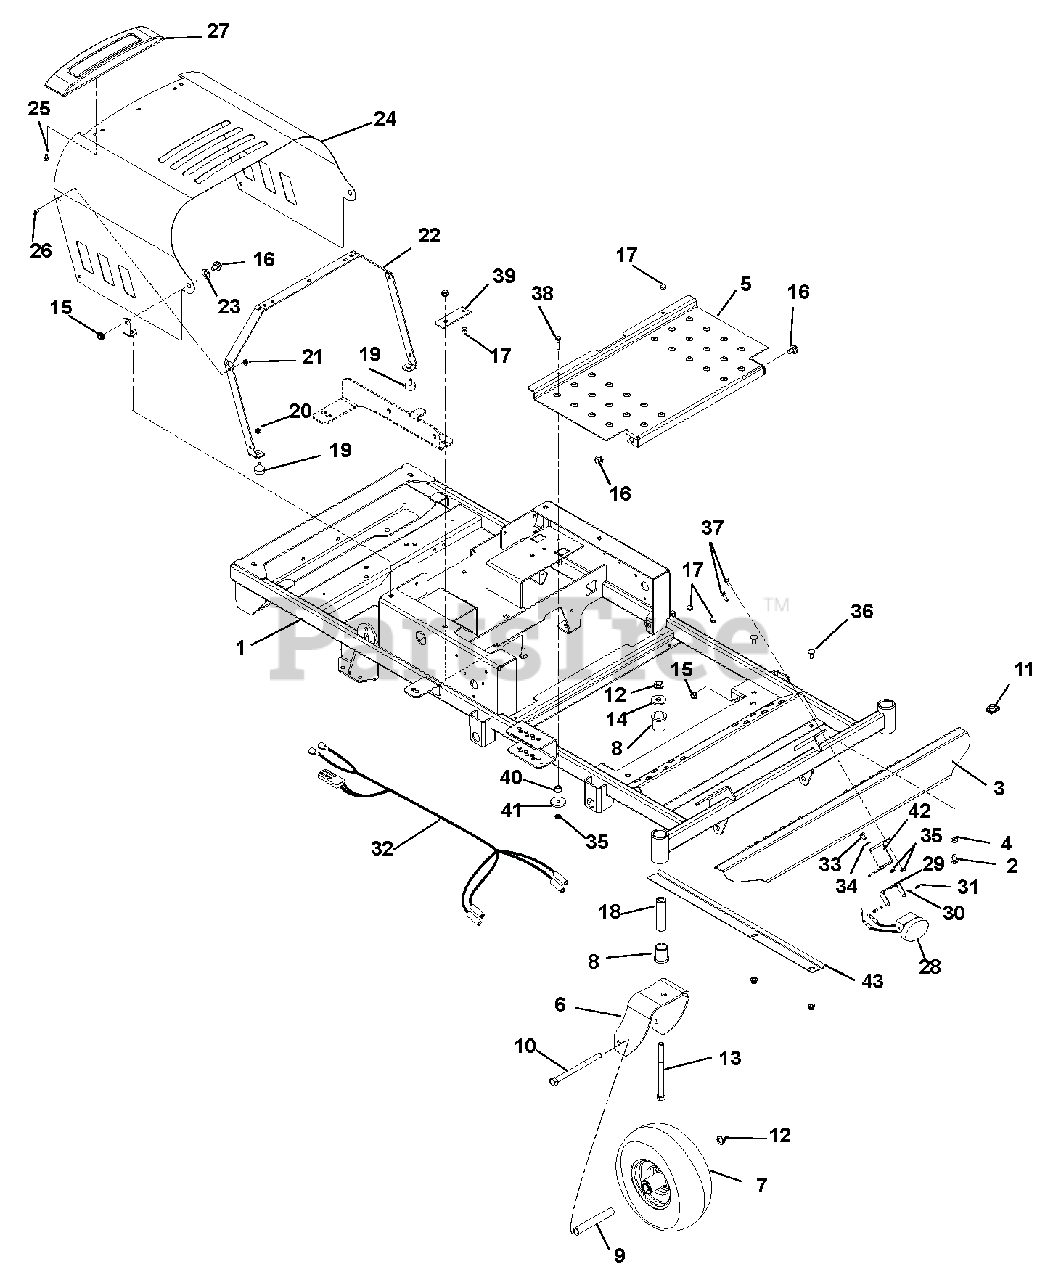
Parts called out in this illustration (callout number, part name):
1	WMT, FRAME XL
2	@BLT-HEX .38-16X1.00 GR5 YWZC
3	WMT, FOOTREST
4	@WSHR-LK .38X.094 REG YWZC
5	DECK ACCESS PANEL
6	CASTER FORK WELDMENT
7	TIRE/WHEEL ASSY, 11X4-5
8	BSHG-FLG 1.00X1.25X1.50X1.50EP
9	SPACER, ROLLED WHEEL
10	@BLT-HEX .50-13X6.50 GR5 YWZC
11	NUT-RTNR .375-16X.37
12	@NUT-LK-TOP-FLG .50-13 YWZC
13	@BLT-HEX .50-13X5.00 GR5 YWZC
14	WSHR-FL-STL.511X1.441X.125 YWZ
15	@NUT-LK-TOP-FLG .38-16 YWZC
16	BOLT-SHLDR .375-16X.150
17	BUMPER GROMMET
18	SPACER, CASTER .50X1.00X1.84
19	BUMPER, RUBBER
20	@NUT-LK-TOP-FLG .31-18 YWZC
21	@NUT-LK-TOP-FLG .25-20 YWZC
22	HOOD STRAP
23	WSHR-FL-NYL .518X1.000X.080
24	HOOD-ZTXL
25	SCR-.25X.62 PN HD BOSSSCREW YZ
26	@BLT-RDHDSQNK .25-20X.50 G5YZ
27	TRIM-ZOOM XL HOOD ARIENS
28	KIT, ZOOM/ZT XL LIGHT
29	WMT, LIGHT BRACKET
30	WSHR-LK 4MMX1MM REG CL ZINC
31	SCREW-M4X.07X8 SHCS CLZNC
32	HARNESS,MINI-Z HEADLIGHT
33	SCR-CAP BTHD.31-18X.50 GR5 YZ
34	@WSHR-LK .31X.078 REG YWZC
35	@NUT-LK-NYL-FLG .25-20 YWZC
36	@BLT-RDHDSQNK .31-18X.75 G5YZ
37	@BLT-HEX .25-20X.75 GR5 YWZC
38	@BLT-HEX .25-20X1.25 GR5 YWZC
39	STRAP, SEAT HOLD DOWN (CE)
40	SPACER .325 X.625 X.455
41	WSHR-FL-STL .281X1.50X.187
42	BRACKET, LIGHT MOUNT
43	BRACKET, LIGHT HARNESS
